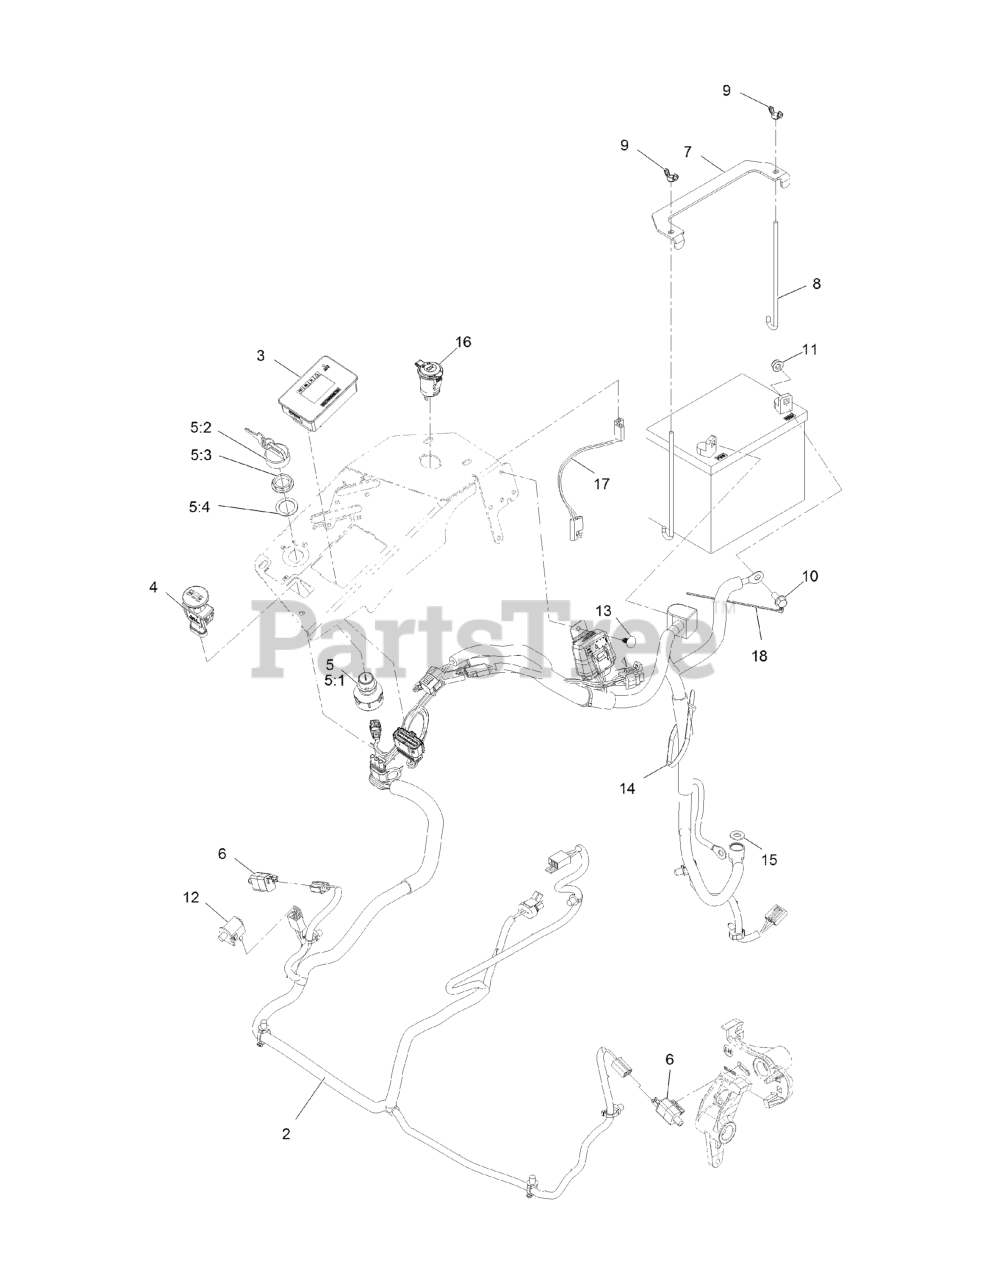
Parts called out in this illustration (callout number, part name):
2	WIRE HARNESS ASM
3	Meter-Hour
4	SWITCH-PTO, SEALED
5	IGNITION SWITCH ASM
5:1	Switch-Ignition
5:2	NUT-MOUNTING
5:3	IGNITION KEY SET
5:4	WASHER-BACKUP
7	STRAP-TIE DOWN, BATTERY
8	BOLT-HOLDDOWN
9	WINGNUT
10	SCREW-HHF
11	NUT-HF, NI
12	SWITCH-BAIL
13	PLUG-PLASTIC
14	TIE-PLASTIC
15	WASHER-FLAT
16	PORT-POWER, 12V
17	HARNESS-RECEPTACLE, 12V
18	TIE-CABLE
